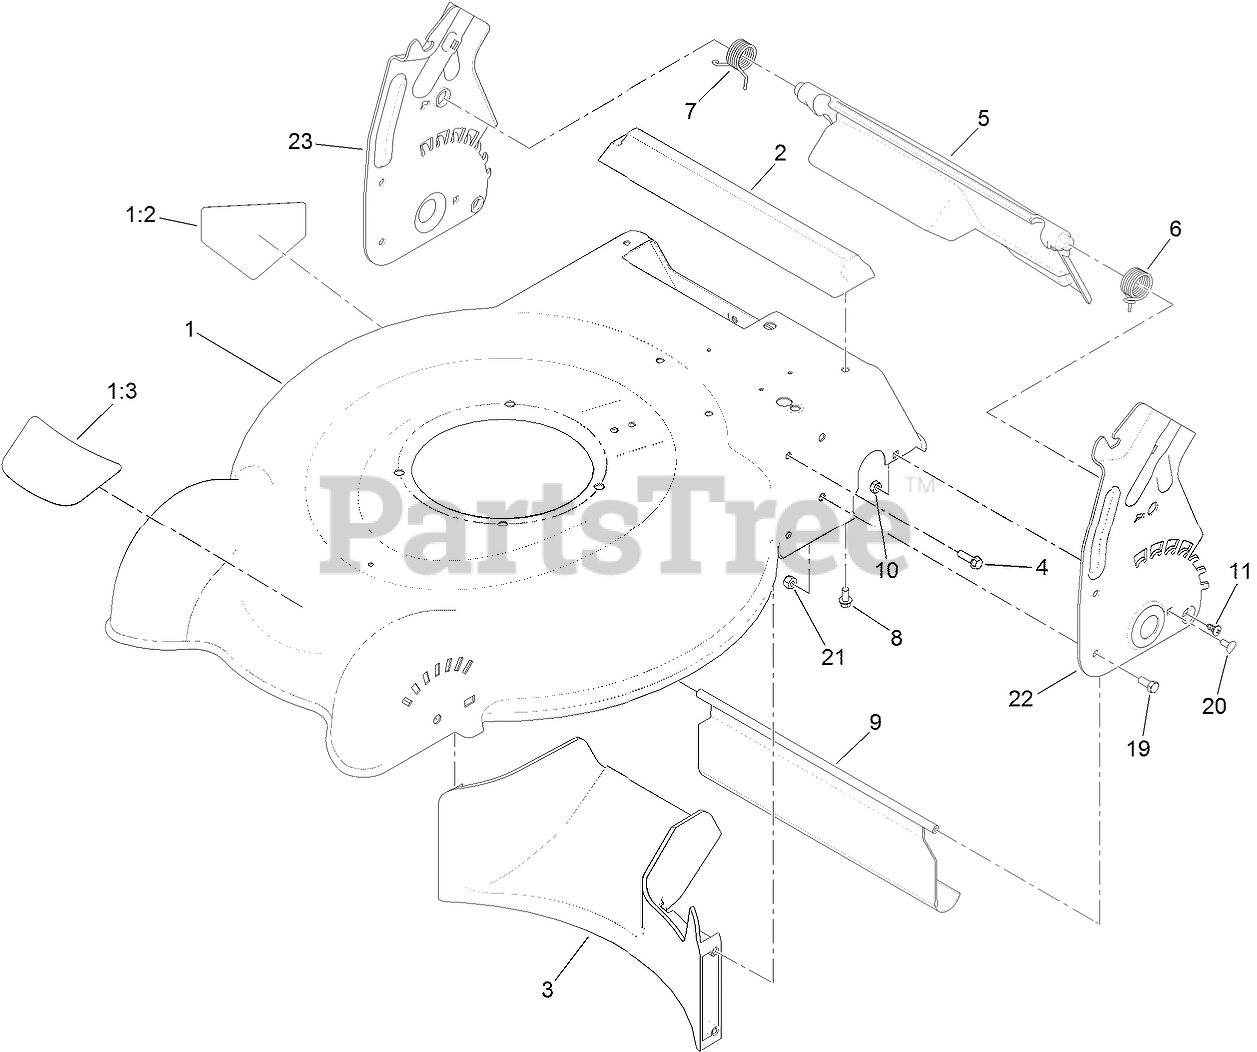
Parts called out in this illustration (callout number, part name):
1	HOUSING ASM
1:2	DECAL-DANGER
1:3	DECAL-DECK
2	CHUTE-REAR
3	BAFFLE-REAR
4	SCREW-HWH
5	Rear Deflector ASM
6	SPRING-TORSION, LH
7	SPRING-TORSION, RH
8	SCREW-PLASTITE
9	SHIELD-TRAILING
10	NUT-LOCK, NI
11	SCREW-PTH
19	SCREW-HH
20	SCREW-CARR
21	NUT-LOCK, NI
22	PLATE-HOC, LH
23	PLATE-HOC, RH
